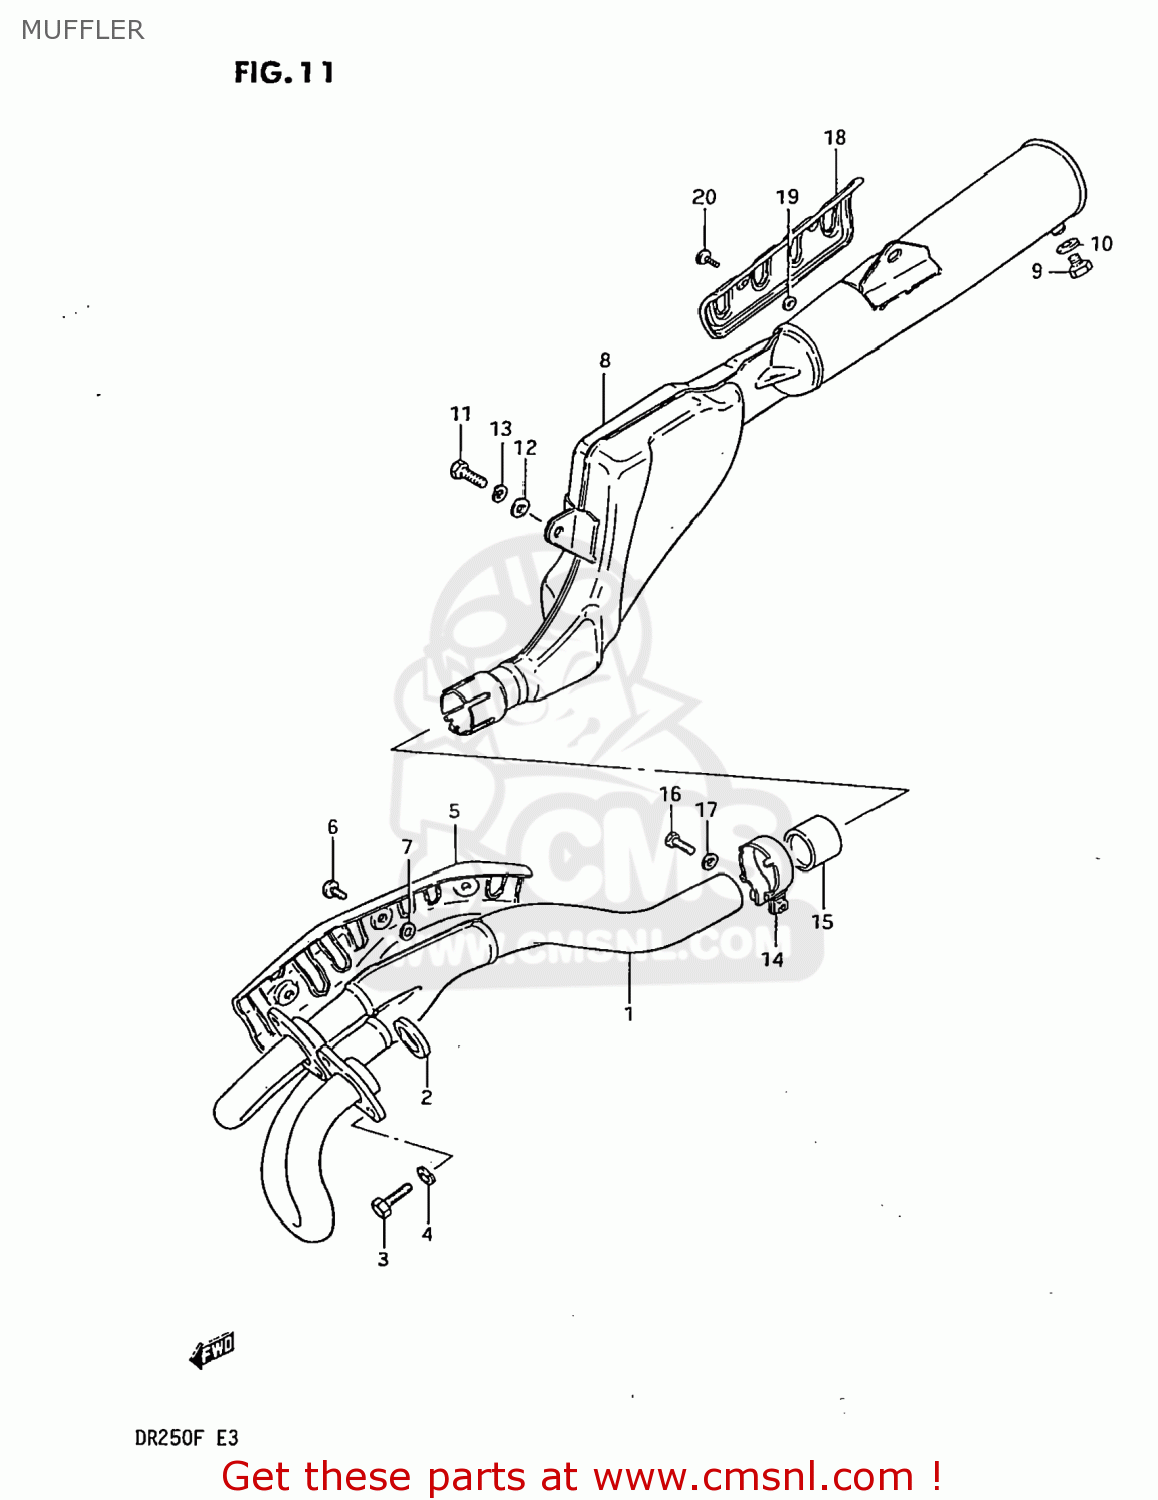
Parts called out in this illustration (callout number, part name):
1	PIPE,EXHAUST
2	GASKET,EXHAUST PIPE (NAS)
3	BOLT
4	WASHER,LOCK
5	COVER,EXHAUST PIPE
6	SCREW
7	GASKET 6.2X12X1.5 (MCA)
8	MUFFLER ASSY
9	PLUG(12X9)
10	GASKET(12.1X16.2X3.7) (NAS)
11	BOLT
12	WASHER
13	WASHER,LOCK,8.
14	CLAMP
15	CONNECTOR,MUFFLER
16	BOLT 8X35
17	WASHER
18	COVER,MUFFLER
19	GASKET 6.2X12X1.5 (MCA)
20	SCREW
